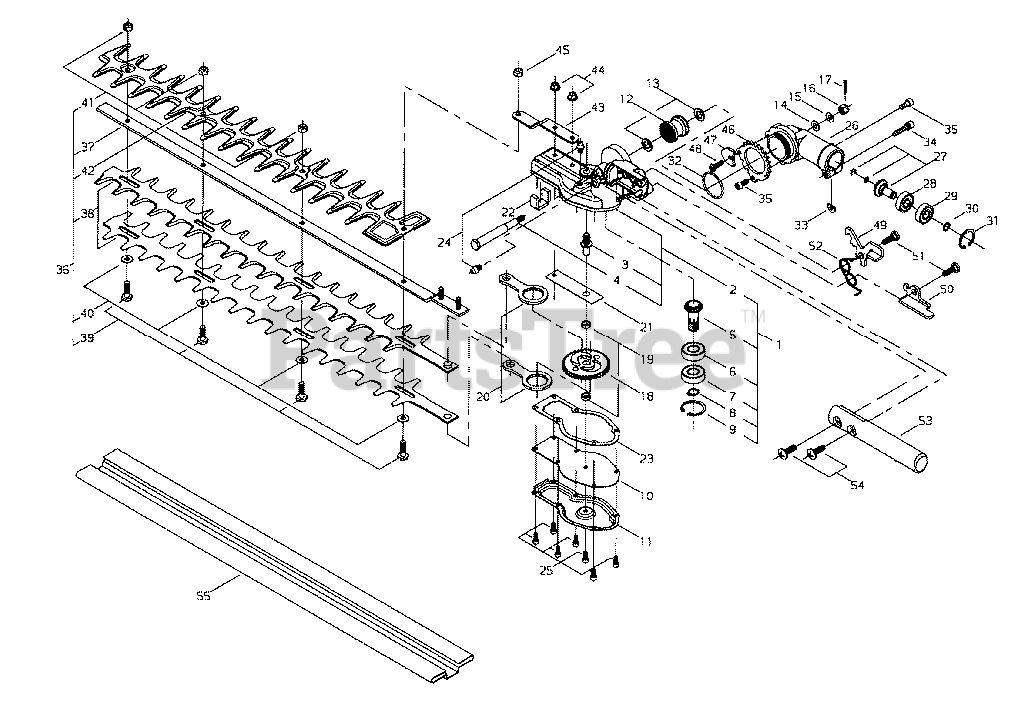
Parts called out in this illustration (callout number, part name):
1	GEAR CASE ASSY
2	CASE, GEAR - LOWER
3	PIPE, MAIN
4	SHAFT
5	GEAR - SHAFT
6	BEARING, BALL - 6001
7	BEARING, BALL - 6001ZZ
8	RING, RETAINING - 12
9	RING, RETAINING - 28
10	PLATE, GEAR CASE
11	CASE, GEAR - LOWER
12	GEAR SET - BEVEL
13	COLLAR
14	WASHER - 6
15	WASHER - CONICAL
16	NUT - CASTLE
17	PIN, SPLIT
18	CAM GEAR
19	SPACER
20	ROD, CONNECTING
21	PLATE, GUIDE
22	SEAL, FELT
23	GASKET
24	FITTING, GREASE
25	SCREW - 4X10
26	CASE, GEAR - UPPER
27	GEAR - BEVEL
28	BEARING, BALL - 609
29	BEARING, BALL - 609ZZ
30	RING, RETAINING
31	RING, RETAINING - 24
32	O-RING
33	SHIM
34	SCREW - 5X25
35	SCREW - 5X12
36	BLADE KIT - 22" (55cm)
37	GUIDE BAR - 22" (55cm)
38	BLADE KIT - 22" (55cm) CHROME
39	BOLT - 6X20
40	WASHER - 6
41	LOCKNUT - 6
42	GUARD, CUTTER BLADE
43	BRACKET, CUTTER
44	NUT - 5 -- FLANGE
45	LOCKNUT - 6
46	PLATE, ADJUST
47	STOPPER PLATE
48	SCREW
49	LEVER, LOCK
50	LEVER, LOCK
51	SCREW
52	SPRING
53	LEVER, ADJUSTMENT
54	SCREW - 6X20
55	COVER, BLADE
